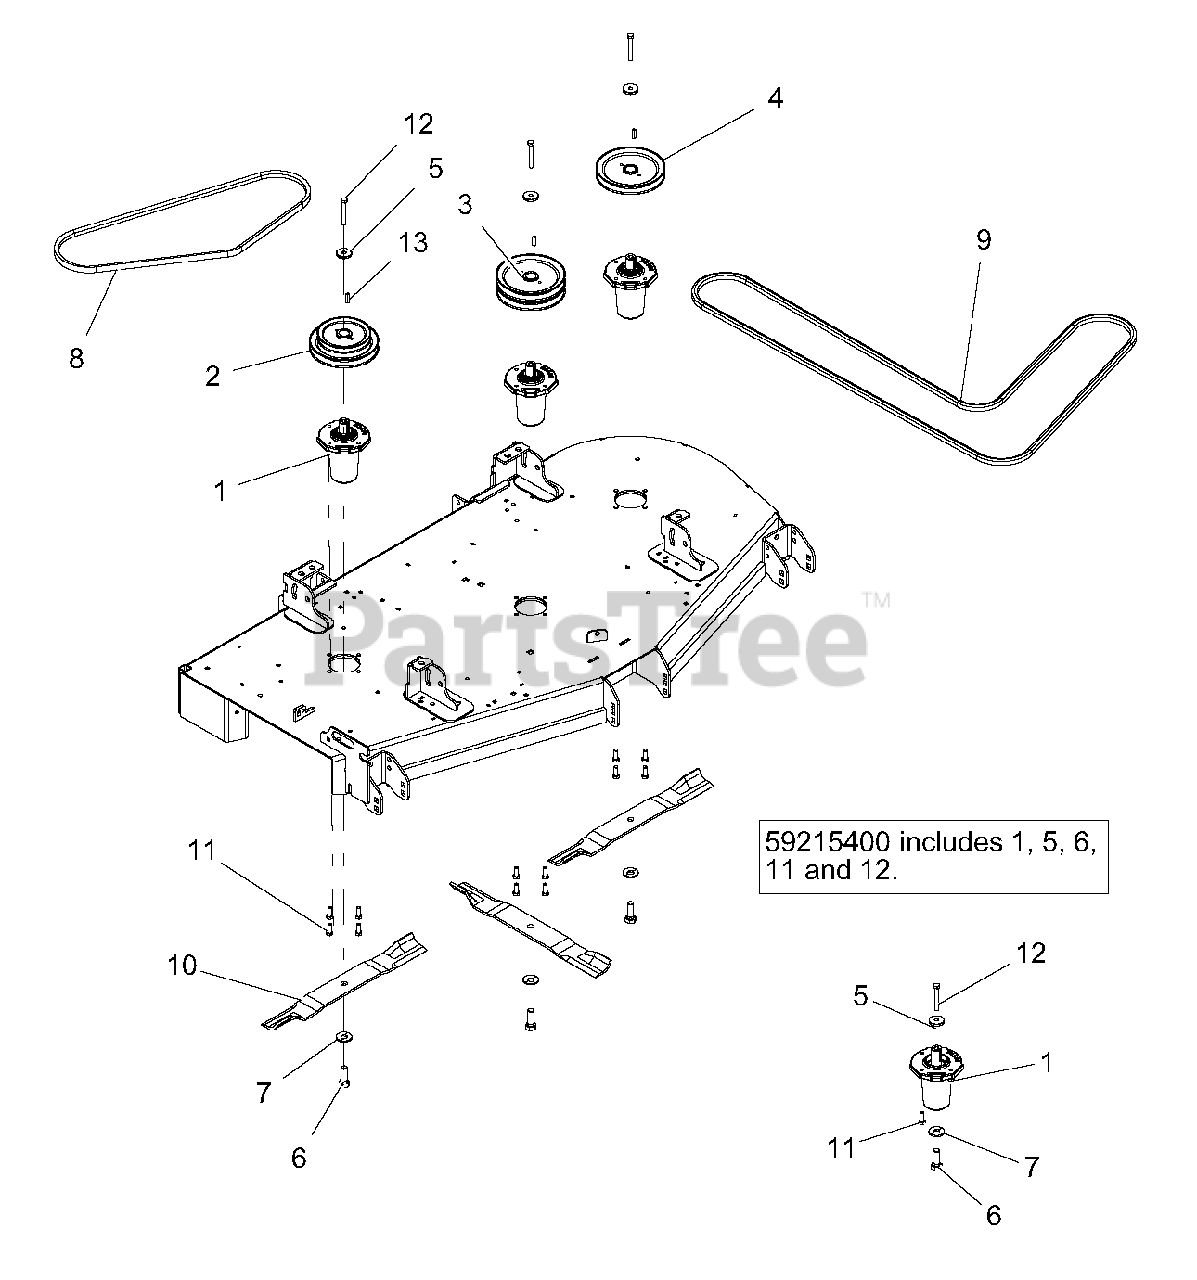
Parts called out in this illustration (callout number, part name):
1	ASM, SPINDLE - G3500
2	PULLEY, DOUBLE -1" ID X 6.75" & 5.25" OD
3	PULLEY, DOUBLE 1"ID X 6.75"OD-BLACK
4	PULLEY, V-1" ID X 6.75" OD-BLACK
5	RETAINER, SHEAVE SPINDLE
6	BLT, HEX .62-18X1.75 GR8 YWZC
7	WSHR, BLVL .63X1.625X.14
8	BELT, B 63.00 RAW COGGED
9	BELT, BB 133.00 WRAPPED HEX
10	BLADE, MOWER 60"
11	BLT-HEX .38-16X1.00 GR5 YWZC EP30
12	BLT-HEX .38-16X2.75 GR8 YWZC
13	KEY-SQ .250X.250X1.00 RC 40-50
